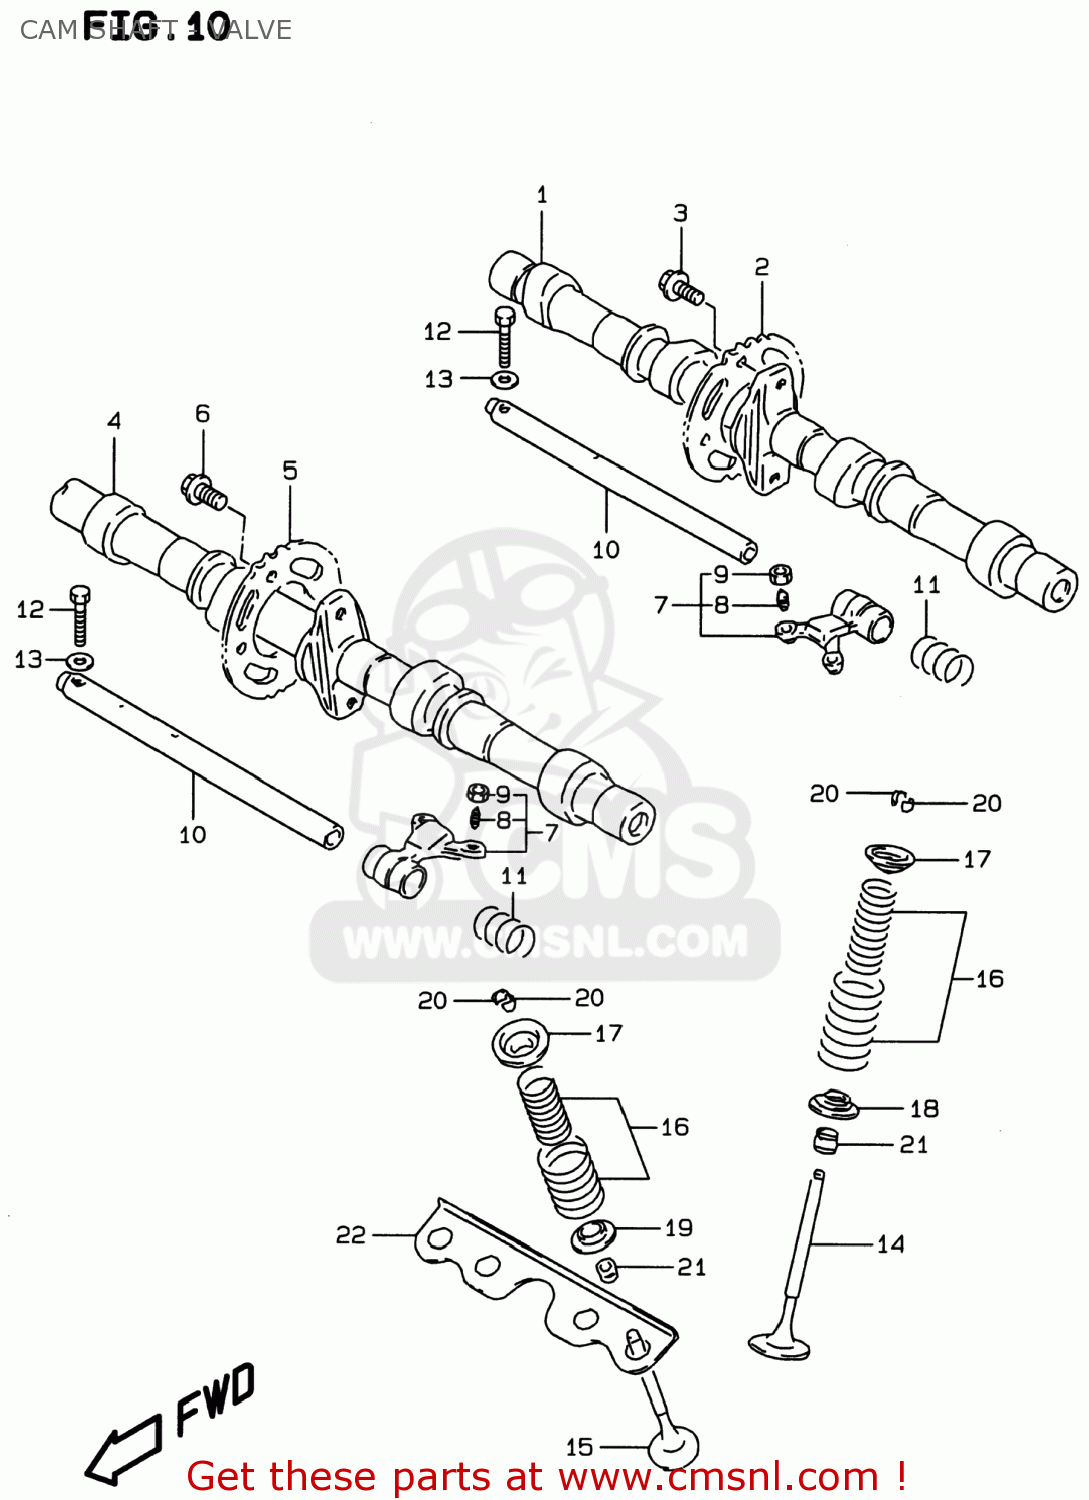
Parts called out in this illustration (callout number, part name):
1	CAMSHAFT,INTAKE
2	SPROCKET,CAMSHAFT
3	BOLT(7X11)
4	CAMSHAFT,EXHAUST
5	SPROCKET,CAMSHAFT
6	BOLT(7X11)
7	ARM,VALVE ROCKER
8	SCREW,TAPPET ADJUSTING
9	NUT,TAPPET ADJUSTING
10	SHAFT,VALVE ROCKER ARM
11	SPRING
12	BOLT
13	WASHER
14	VALVE,INTAKE
15	VALVE,EXHAUST
16	SPRING SET,VALVE
17	RETAINER,VALVE SPRING
18	SEAT,VALVE SPRING
19	SEAT,VALVE SPRING EXH INNER
20	COTTER VALVE
21	SEAL,OIL(5X10X9.7)
22	PLATE,VALVE SEAT
